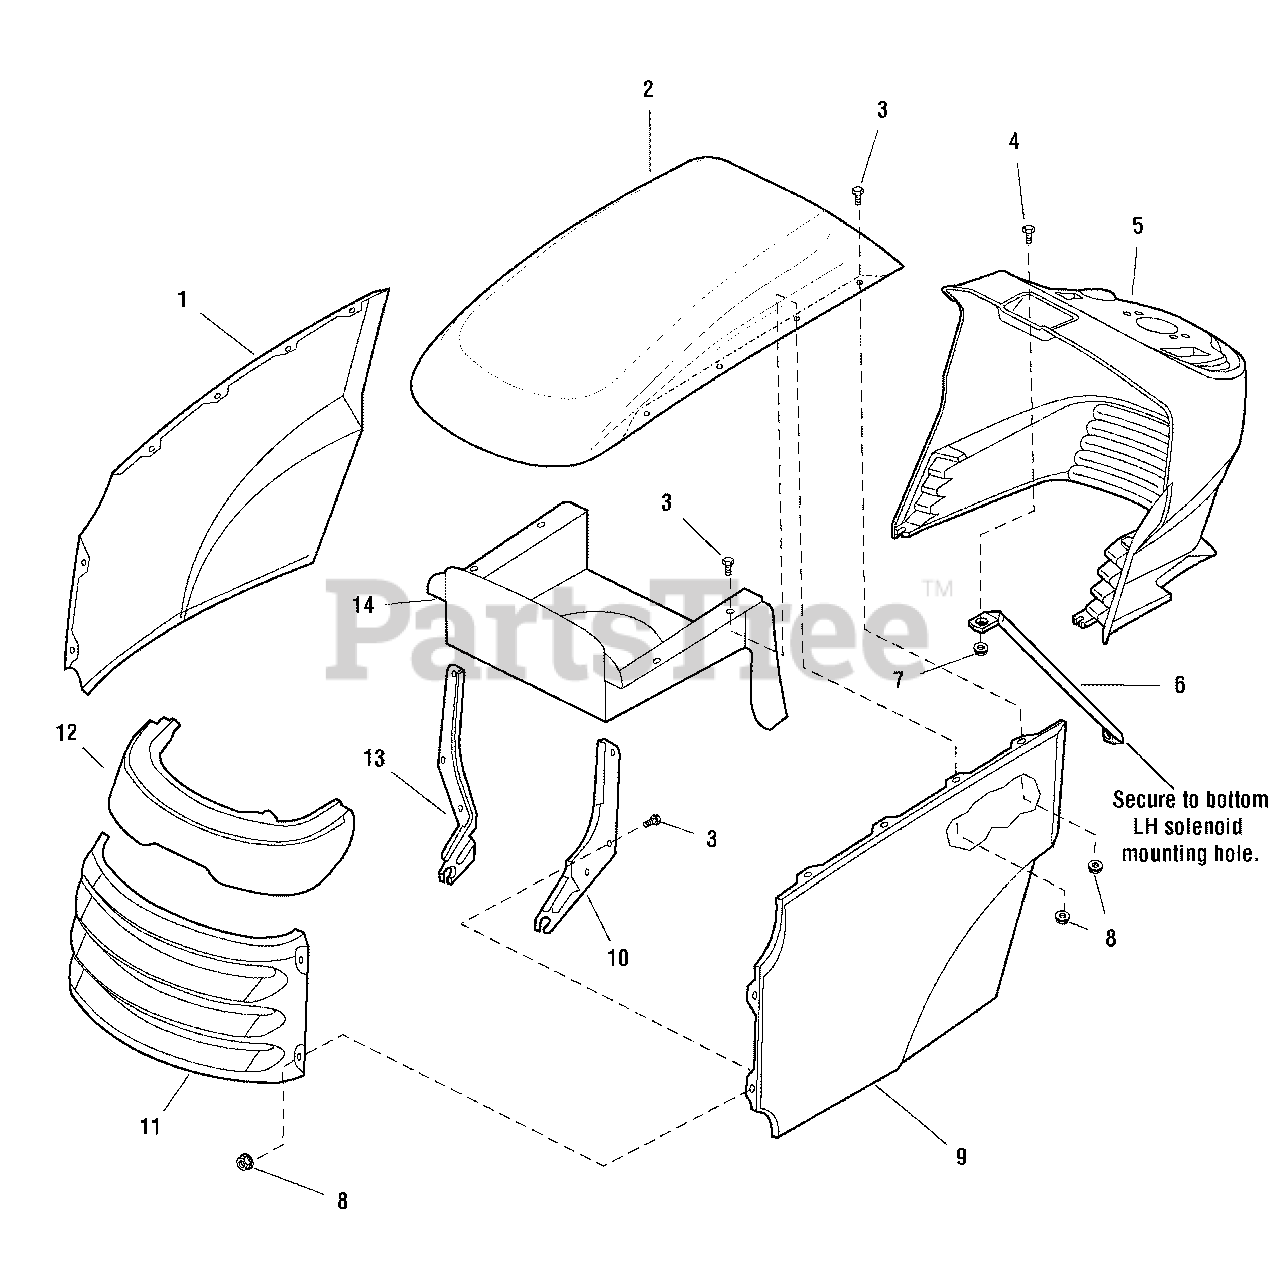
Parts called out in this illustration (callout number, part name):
1	PANEL, RH Side, Red
2	HOOD, Red
3	CAPSCREW, Hex Flange Whiz Lock, 1/4-20 x 5/8
4	SCREW, Pan Head Phillips, #10-24 x 1/2
5	DASHBOARD
6	ROD, Dash Support
7	NUT, Hex Lock, w/Nylon Insert, 10-24
8	NUT, Hex Flange Whiz Lock, 1/4-20, Large, Black
9	PANEL, LH Side, Red
10	HINGE, LH
11	GRILLE, Red
12	HEADLIGHT ASSEMBLY, 4 Bulb (See Electrical Group for internal components)
13	HINGE, RH
14	DUCT, Air Inlet
